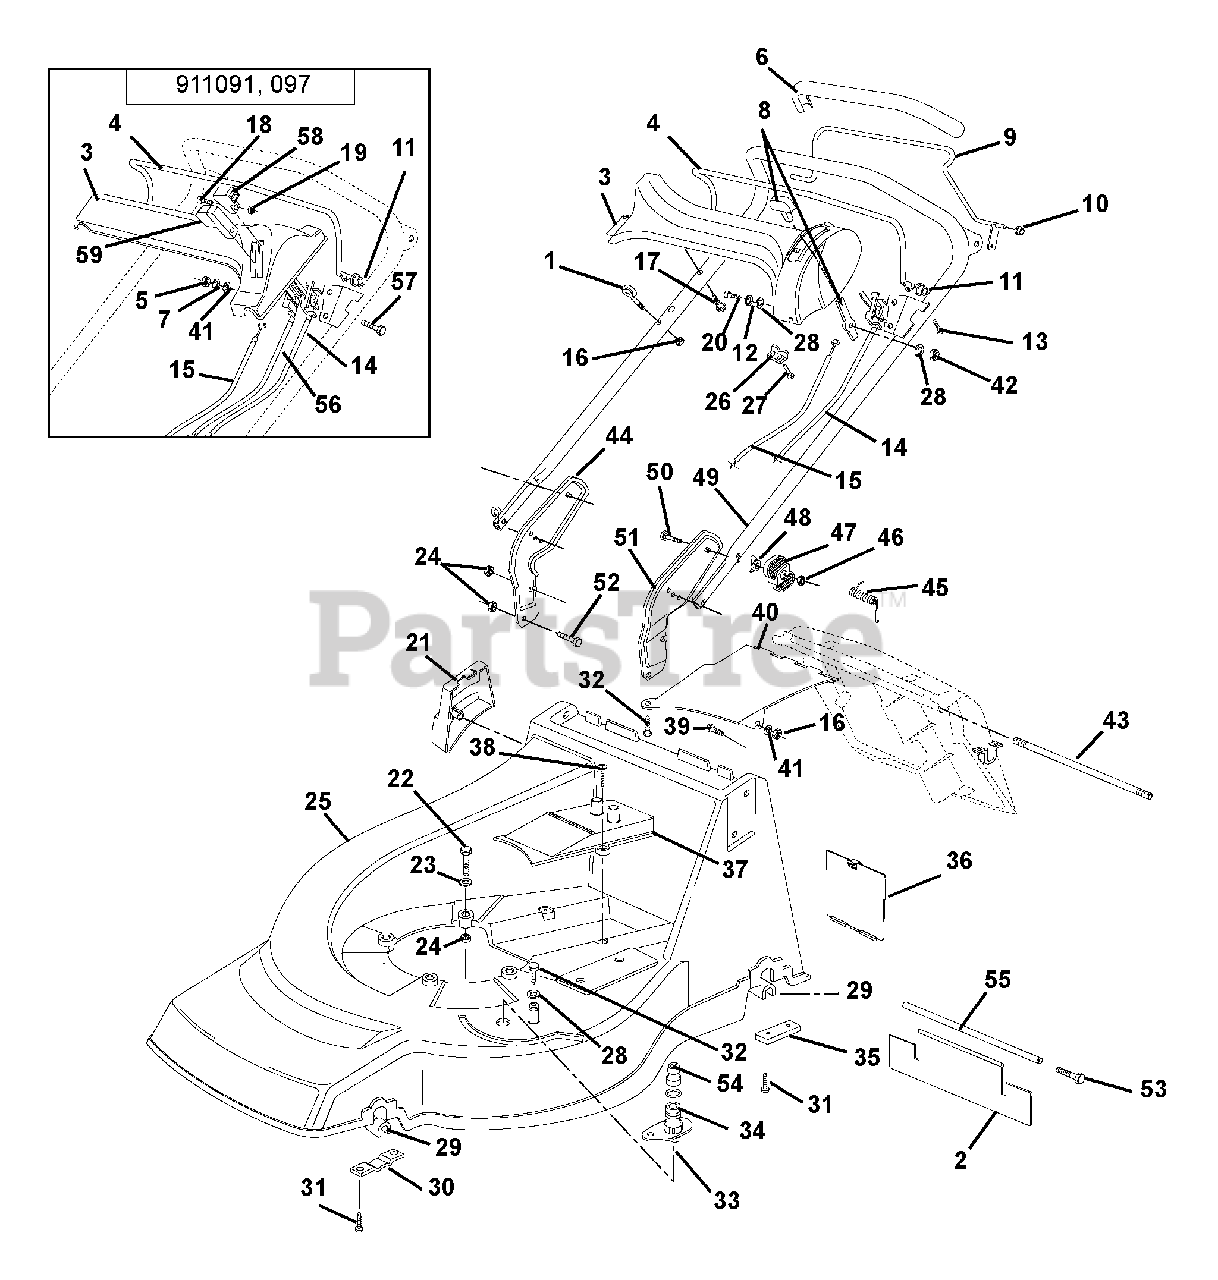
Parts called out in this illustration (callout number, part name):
1	GUIDE, ROPE
2	REAR PROTECTIVE GUARD, S.P.
3	DASHBOARD - BLACK
3	DASH BOARD, 3 SPEED IMPORT BLK
4	BAIL, ENGINE
5	NUT, 5MM ZINC
6	GRIP, HAND BLACK
7	WSHR-LK 5MM ZINC
8	LEVER, THROTTLE W/KNOB
9	BAIL, TRACTION
10	BUSHING
11	BUSHING
12	WASHER M6
13	SCREW 4.8X38
14	CABLE, THROTTLE
15	CABLE, MOTOR BRAKE
15	CABLE,MOTOR BRAKE (HONDA)
16	NUT M5
18	SCREW, 4MM X 12MM PAN HEAD ZC
19	NUT, METRIC 4 MM
20	SCREW M6X25
21	PROTECTION
22	SCREW M8X60
23	WASHER M8 8.4X16X1.6
25	21" DECK W/DECALS IMPORT
26	PLATE, DASHBOARD CABLE
27	SCREW 3.5X16
28	WASHER M6 6.6X18X2
29	BRASS, FRONT
29	BRASS, REAR
30	PLATE, FRONT AXLE
31	SCREW 5.5X19
32	SCREW 5.5X16
33	WASHING CONNECTION
35	PLATE, REAR AXLE (PUSH)
35	PLATE, REAR AXLE (SP)
36	DOOR, INSPECTION
37	PROTECTION, BELT
38	SCREW 5.5X19
39	SCREW M5X12
40	CONVEYOR
41	WASHER M5 5.5X15X1.6
44	BRACKET, HANDLEBAR RIGHT
46	NUT M8
49	HANDLEBAR, PUSH
49	HANDLEBAR, 3-SPD IMPORT ALUM
50	SCREW M8X55
51	BRACKET, HANDLEBAR LEFT
52	SCREW M8X25
54	Coupling, Hose (Not Supplied)
55	ROD, TRIALING SHIELD
56	CABLE, SPEED CTRL 3SPD IMPORT
57	BLT-HEX 5MM X 16MM BLK ZINC
58	KNOB, THROTTLE 3-SPD IMPORT
59	KNOB, SPEED SELECT 3SPD IMPORT
114	CABLE, THROTTLE 3SPD IMPORT
